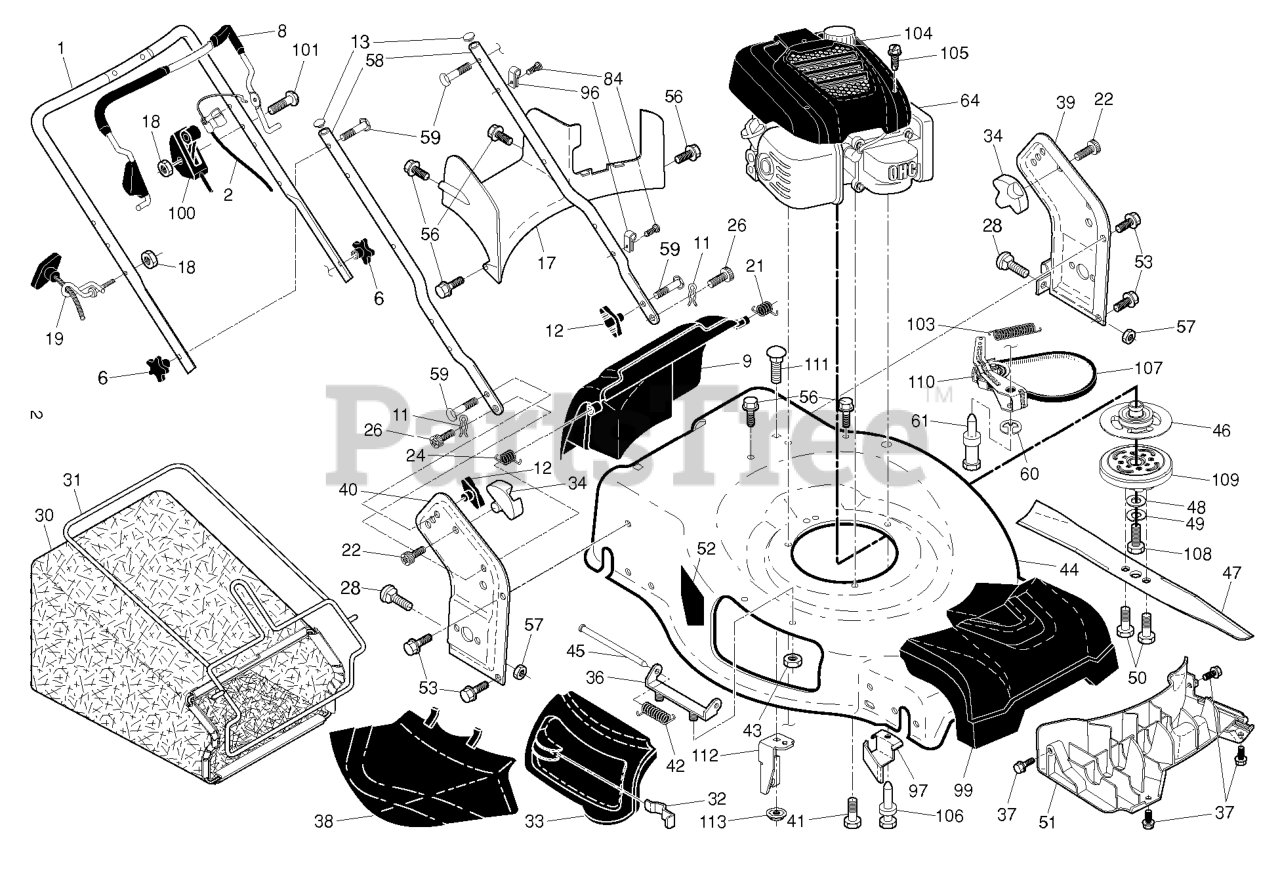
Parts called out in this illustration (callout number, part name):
1	HANDLE.UPPER.3.POS.BS.AW2.GREY
2	CABLE.BBC.22+.AW2.BS.ERGO.WALK
6	KNOB.HANDLE.PLASTIC.STAR.BLACK
8	RP.BAIL.ASM.BBC.ERGO.ORG/BL
9	DOOR.REAR.ASM.22+.HUSQ.FG/RGD
11	COTTER.HAIRPIN.DOOR/HANDLE.PIV
12	KNOB, DEFLECTOR
13	PLUG.PLASTIC.7/8".14-20.GAUGE
17	BAFFLE.REAR.22+RGD.AWD.PLASTIC
18	NUT
19	RB GUIDE.ROPE.STD.BLK.ZIN WSL
21	SPRING.LH.BLACK
22	SCREW.PAN.HEAD.#10
24	SPRING.RH.GRAY
26	SCREW,DOOR/HANDLE.PIVOT
28	BOLT
30	GBAG.A3610247T.SILV.HUSWT.BLUE
31	RB FRAME.GBAG.22PLUS
32	LATCH.DOOR.ZINC
33	DOOR.MULCH.22 PLUS.HUSQ.GREY
34	BRACKET.GRASSBAG.ATTACHING.BLK
36	BRACKET.ASM.HINGE.21.FWGD.
37	SCREW.HI-LO.5/16 X.75
38	DEFLECTOR.CLIPPING.22.BLACK
39	BRACKET.ASM.HNDL.LT.22+.GREY
40	BRACKET.ASM.HNDL.RT.22+.GREY
41	BOLT 3/8-16X1-1/8
42	SPRING.TORSION
43	NUT.HEX.FLANGE.1/4
45	ROD.HINGE.21
46	PULLEY.BBC.DRIVING
47	BLADE.22.4-N-1.BBC.
48	WASHER.CRANK.BOLT
49	LOCKWASHER
50	BOLT.BLADE
51	BAFFLE.FRONT.22+PLASTIC.(2 2)
52	DECAL.INTERNATIONL.CUTFINGER
53	BOLT.5/16HEX.WHS.HD
56	SCREW.HX.13X.750
57	NUT.FLANGE.5/16
58	HANDLE.LOWER.22+BT.2PC.GRY
59	BOLT, HANDLE 5/16-18X1.75
60	E-RING.12MM.SHAFT
61	BOLT.BBC.TENSION.PIVOT
84	FASTENER.PUSH.O.250X0.783
96	CLIP.CABLE.BLK
97	BRACKET.BELT.GUIDE.22+.BZP
99	COVER.ASM.FRONT.SHROUD.HUSQ.
100	CONTROL.THROTTLE.HOND.BBC.58.5
103	SPRING.BRAKE.RESET
106	BOLT.BRAKE.RESET.SPRING
107	BELT.COG.BBC
108	SCREW, HEX HD 3/8-24 X 1-3/8
109	HUB.FREE.BBC.ASSEMBLY(2 2MC)
110	ARM.BBC.TNSION.ARM.PULL(2 2MC)
112	BRACKET.CABLE MOUNTING.22+
113	NUT.FLANGE.1-4-20-SERR
